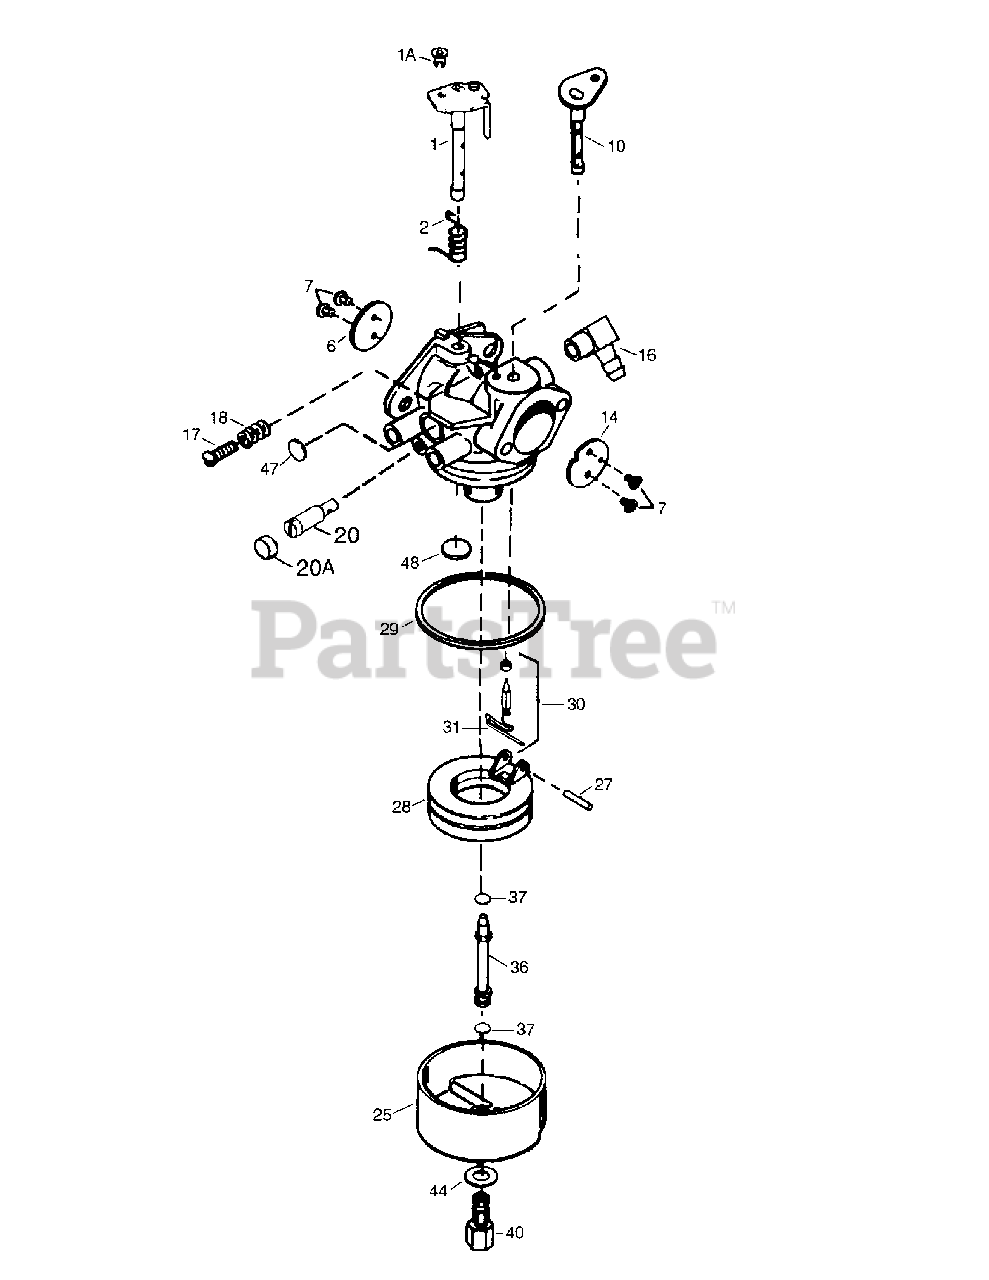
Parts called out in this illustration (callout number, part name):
1	Throttle Shaft & Lever Assy.
2	Throttle Return Spring
6	Throttle Shutter
7	*Shutter Screw
10	Choke Shaft & Lever Assy.
14	Choke Shutter
16	Fuel Fitting
17	Idle Speed Screw
18	Tension Spring
20	Idle Resrictor Scew
20A	Idle Resrictor Scew Cap
25	Float Bowl Assy.
27	*Float Shaft
28	Float
29	*Float Bowl O-Ring
30	*Inlet Needle, Seat & Clip
31	Spring Clip
36	Main Nozzle Tube
37	*Main Nozzle Tube O-Ring
40	High Speed Bowl Nut
44	Bowl Nut Washer
47	*Welch Plug
48	*Welch Plug
